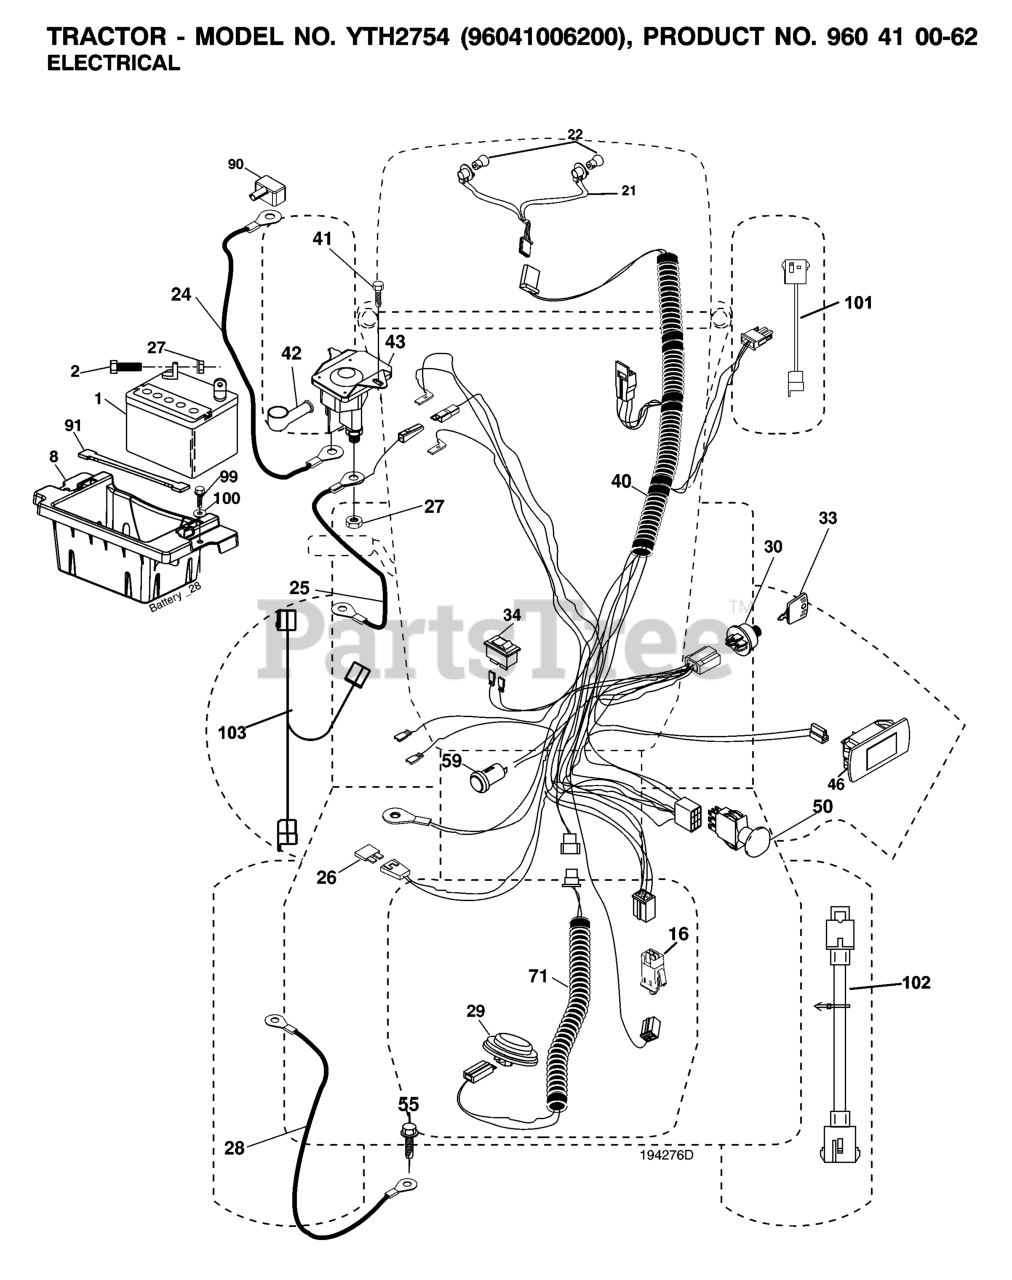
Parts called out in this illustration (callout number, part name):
1	BATTERY 12V .35 AMP
2	BOLT.HEX.1/4.X.3/4.DICHROMATE
8	BOX.BATTERY.MOUNT.FRONT.LT
16	SWITCH INTERLOOK PUSH-IN
21	HARNESS ASSY LIGHT
24	CABLE.BATT.POS.WIRE.TG.DA SOL
25	CABLE.START.RED.17.5".
26	FUSE 20AMP
27	NUT
28	CABLE GROUND 6 GA 21" 90T BLK
29	SWITCH.SEAT.DELTA.OPC.
30	SWITCH.IGN.DELTA.W.LGH.ROS
33	KEY MLD GEN DELTA
40	HARNESS.IGN.DASH.HUQ/P
41	SCREW
42	TERMINAL COVER
43	SOLENOID.W/BRASS.PLUNGER
46	RP.GUAGE.SRVCMNDR.HRMTR.
50	RP.PTO.SWITCH.8 TERMINAL.BLACK
55	SCREW 5/16"
59	OUTLET.12-VOLT
71	HARNESS-CHASSIS SUB
90	COVER.TERMINAL.BATTERY
91	STRAP.BATTERY.MOUNT.FRONT(2 2)
99	SCREW HEXWSHR 1/4-20X3/4
101	PIGTAIL.MATNLK.NEW.HAR
102	HARNESS PIGTAIL PCH TEX ROS
103	HARNESS PIGTAIL 12V OUTLET
